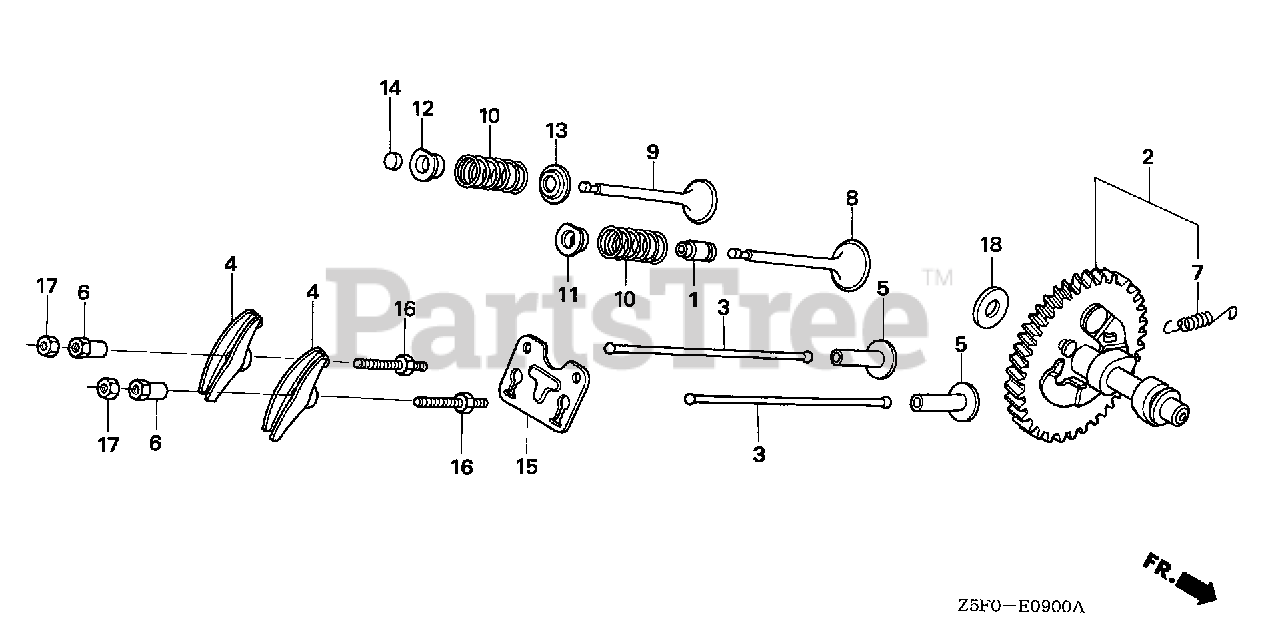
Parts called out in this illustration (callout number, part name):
1	SEAL, VALVE STEM
2	CAMSHAFT (STD) (PRESS FIT CAM)
3	ROD, PUSH
4	ARM, VALVE ROCKER
5	LIFTER, VALVE
6	PIVOT, ROCKER ARM
7	SPRING, WEIGHT RETURN
8	VALVE, IN.
9	VALVE, EX.
10	SPRING, VALVE
11	RETAINER, IN. VALVE SPRING (EXHAUST SIDE)
12	RETAINER, IN. VALVE SPRING (EXHAUST SIDE)
13	SEAT, VALVE SPRING
15	PLATE, PUSH ROD GUIDE
16	BOLT, PIVOT (8MM)
17	NUT, PIVOT ADJ.
